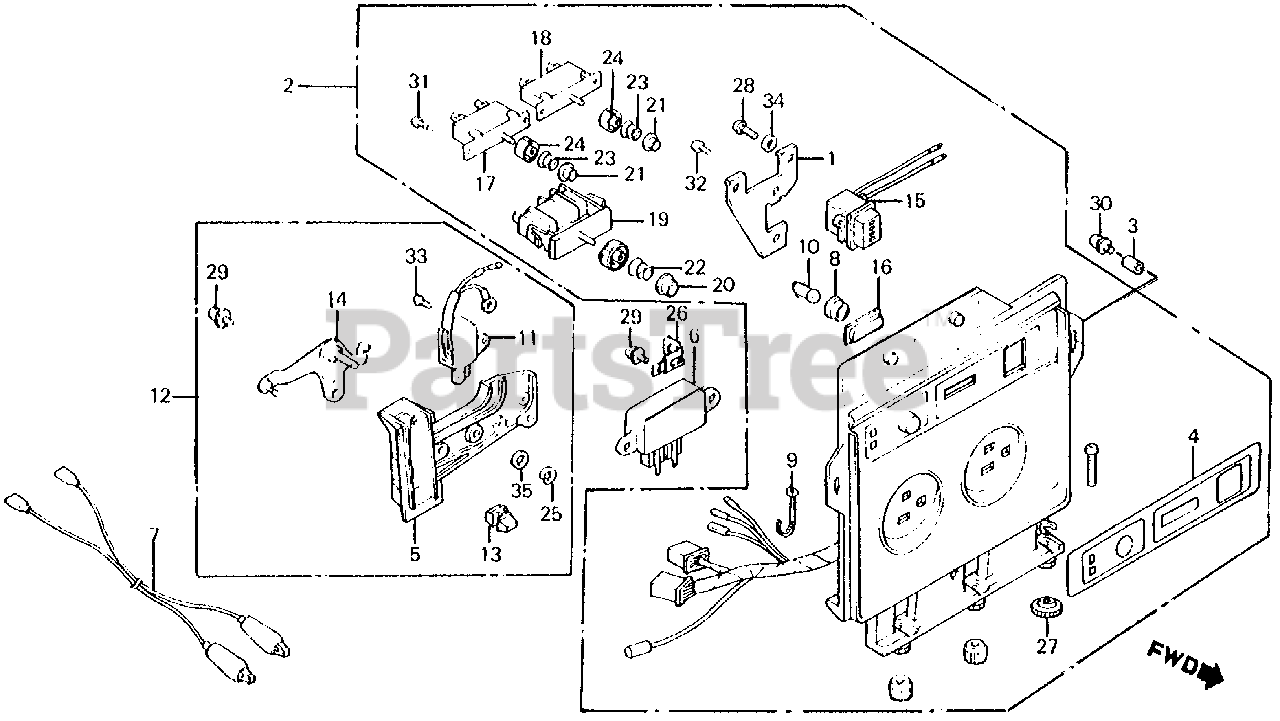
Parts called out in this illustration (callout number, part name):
1	HOLDER, CONNECTOR
2	PANEL ASSY., CONTROL
3	COLLAR, PANEL
4	MARK, PANEL
5	BRACKET, ENGINE SWITCH
6	UNIT ASSY., ALERT TIMER (NOT AVAILABLE)
7	WIRE ASSY., CHARGE
10	BULB, DASH (6V3W) (STANLEY)
11	SWITCH ASSY., STOP
12	BRACKET ASSY., ENGINE SWITCH
13	KNOB, ENGINE SWITCH
14	LEVER, VALVE
15	METER, FREQUENCY
16	LENS, LAMP
17	PROTECTOR, D.C. CIRCUIT (12A)
18	PROTECTOR, CIRCUIT (NOT AVAILABLE)
19	PROTECTOR, CIRCUIT (2A) (NOT AVAILABLE)
20	CAP, BREAKER (NOT AVAILABLE)
21	CAP, BREAKER
22	SPRING, RETURN
23	SPRING, RETURN
24	HOLDER, BREAKER
25	CLIP, LOCK PIN (NOT AVAILABLE)
26	CLIP (2X50)
27	NUT, SPECIAL (6MM)
28	SCREW, PAN (3X8)
29	SCREW-WASHER (5X16)
30	SCREW-WASHER (5X12)
31	SCREW, TAPPING (3X8)
32	SCREW, TAPPING (4X10)
33	SCREW, TAPPING (3X8)
34	WASHER, PLAIN (3MM)
35	WASHER, PLAIN (6MM)
